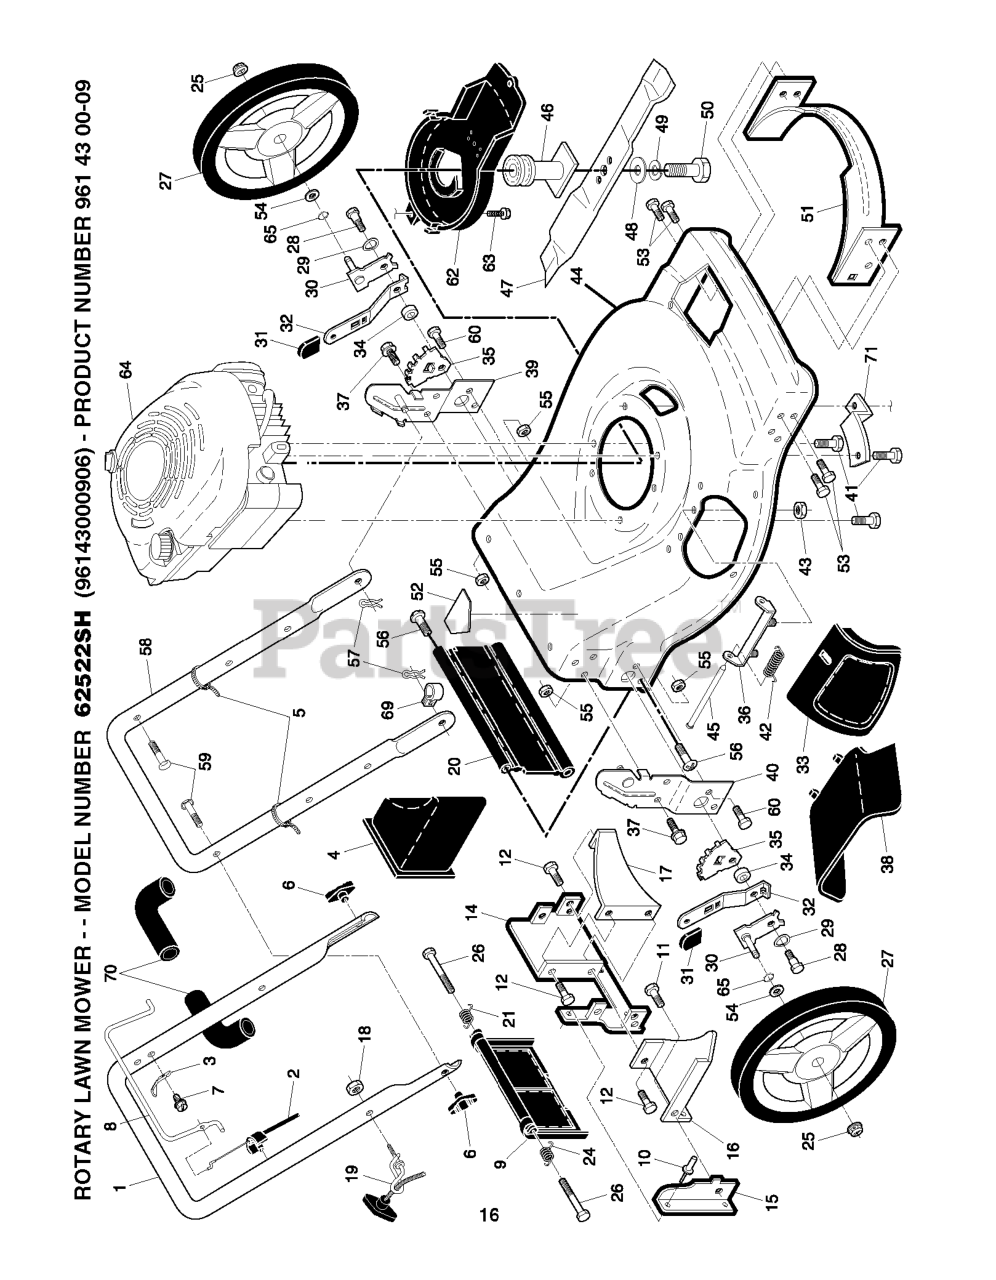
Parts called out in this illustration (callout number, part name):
1	HANDLE.ASM.UP.OFF/EZ.CR.W/GRIP
2	CABLE.ENGINE BRAKE.MZR
3	BRACKET UPSTOP
4	PLUG.MULCH.22RD
5	TIE GUIDE
6	HNDL.KNOB.GRAY
8	BAIL.DSTRT.FL.AW.CREAS.ORANGE
9	REAR DOOR ASSY
10	RIVET BLIND
11	SCREW.HXTAP.10-24
14	PLATE.BACK
15	SIDE BAFFLE
16	DISCHARGE BAFFLE
17	REAR BAFFLE
18	NUT
19	RB GUIDE.ROPE.STD.BLK.ZIN WSL
20	SKIRT
21	SPRING.LH.22.REAR.DOOR.EZ.EMPT
24	SPRING.RH.22.REAR.DOOR.EZ.
25	NUT
27	RP.WHEEL.12X1.75H 3 SPOKE.RAD
28	BOLT
29	WASHER.CURVED.CYLINDRICAL
30	ARM.ASM.AXLE.5/9.POS.BZP
31	KNOB.DELUXE.GRAY
32	SELECTOR SPRING
33	DOOR.MULCH.22.REAR.FWGD.GREY
34	SPACER.HEIGHT.ADJUSTER
35	WHEEL ADJ BRACKET
36	BRACKET.ASM.HINGE.21.FWGD.
37	SELF-TAPPING SCREW 5/16-18X3/4
38	DEFLECTOR.CLIPPING.22.GREY
39	BRKT.ASM.HND
40	BRKT.ASM.HND
41	BOLT 3/8-16X1-1/8
42	SPRING.TORSION
43	LOCKNUT.NYLOC.1/4-20
44	KIT, MOWER HOUSING
45	ROD.HINGE.21
46	RP ADAP.BLDE/PULL
47	BLADE.22.MULCH.STANDARD
48	WASHER,HARDEN
49	LOCKWASHER
50	SCREW, HEX HD 3/8-24 X 1-3/8
51	FRONT BAFFLE KIT
52	DANGER DECAL
53	SCREW 1/4X20
54	WASHER.FLAT.1/2
55	LOCKNUT PM
56	HINGE SCREW
57	HAIRPIN COTTER
58	HANDLE
59	BOLT, HANDLE 5/16-18X1.75
61	LOCKNUT PM
62	DEBRIS SHIELD
63	SCREW.HEX.WSH
65	O-RING..070X.487.NEOPRENE
69	CLIP.CABLE.BLK
70	GRIP.HANDLE.FOAM.WIDE.(1 SIDE)
71	BRACKET
